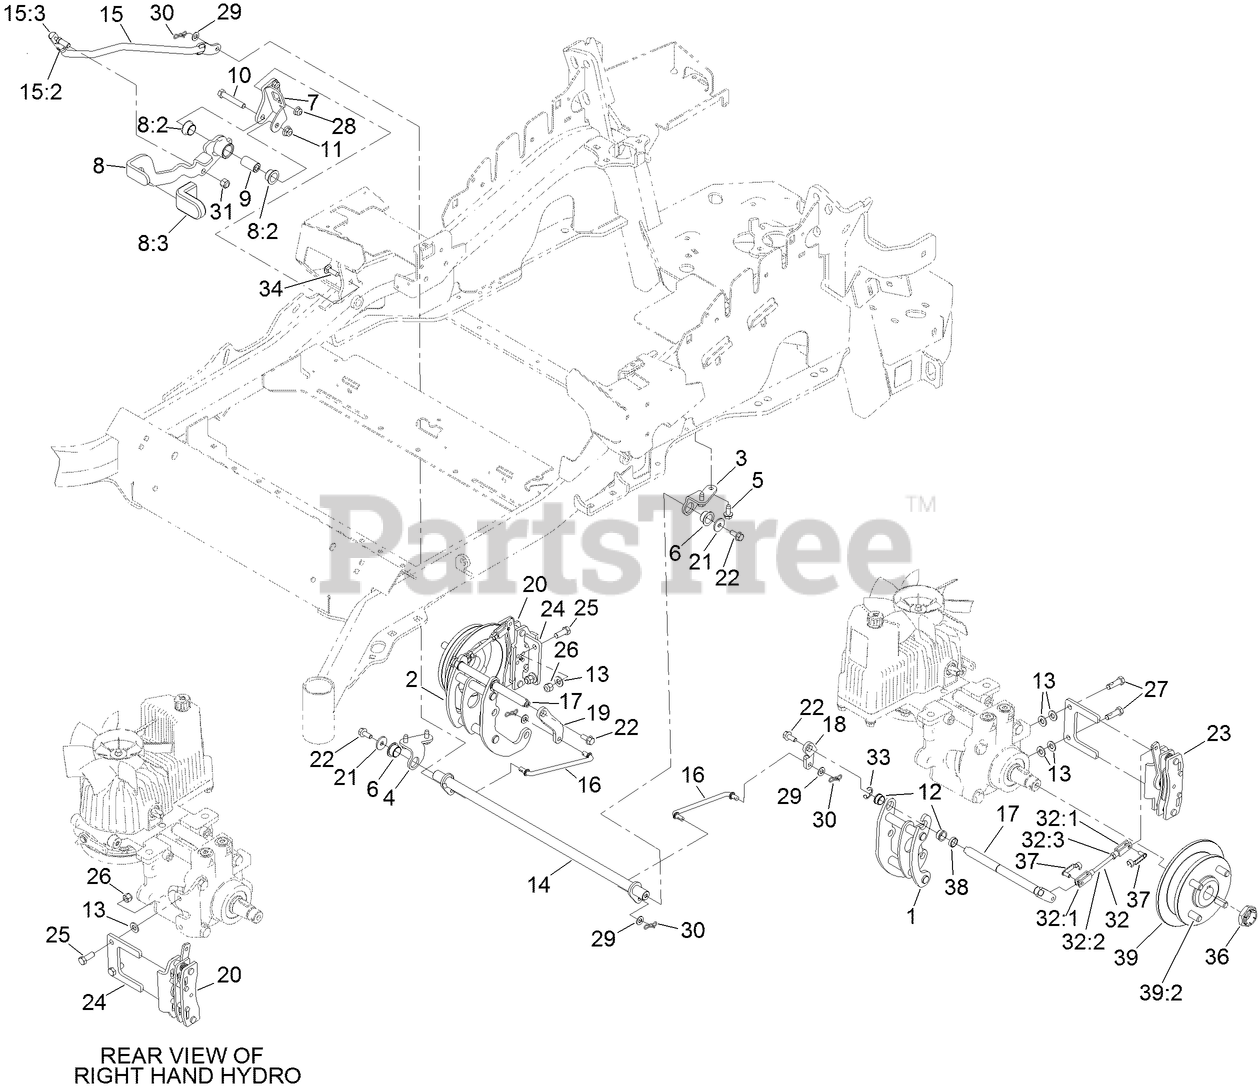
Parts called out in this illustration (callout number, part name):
1	MOUNT-BELLCRANK, LH
2	MOUNT-BELLCRANK, RH
3	MOUNT-PIVOT, LH
4	MOUNT-PIVOT, RH
5	SCREW-HWHTF
6	BUSHING-FLANGE
7	BRACKET-MOUNT
8	BRAKE LEVER ASM W/GRIP M-R
8:2	BUSHING-FLANGE
8:3	GRIP-LEVER
9	HANDLE-PIVOT, BRAKE
10	SCREW-HH
11	NUT-HF, NI
12	BUSHING
13	WASHER-FLAT
14	SHAFT-CROSS
15	ASM, FRONT LINKAGE
15:2	END-TIE ROD, RH
15:3	NUT-HJ
16	LINK-MID
17	BELLCRANK
18	ARM-INNER, LH
19	ARM-INNER, RH
20	CALIPER-BRAKE, RH
21	WASHER-FLAT
22	SCREW-HHF
23	CALIPER-BRAKE, LH
24	PLATE-MOUNT, BRAKE
25	SCREW-HH,
26	NUT-LOCK
27	SCREW-HH, PATCH,
28	NUT-HF, NI
29	WASHER-PLAIN
30	PIN-COTTER, LOCKING
31	NUT-LOCK
32	REAR LINKAGE ASM
32:2	LINKAGE, REAR
32:3	NUT-JAM
33	E-RING
34	BOLT-CARR
36	LOCKNUT
37	PIN-CLEVIS, SPRING
38	SPACER
39	WHEEL HUB ASM
39:2	STUD-WHEEL
